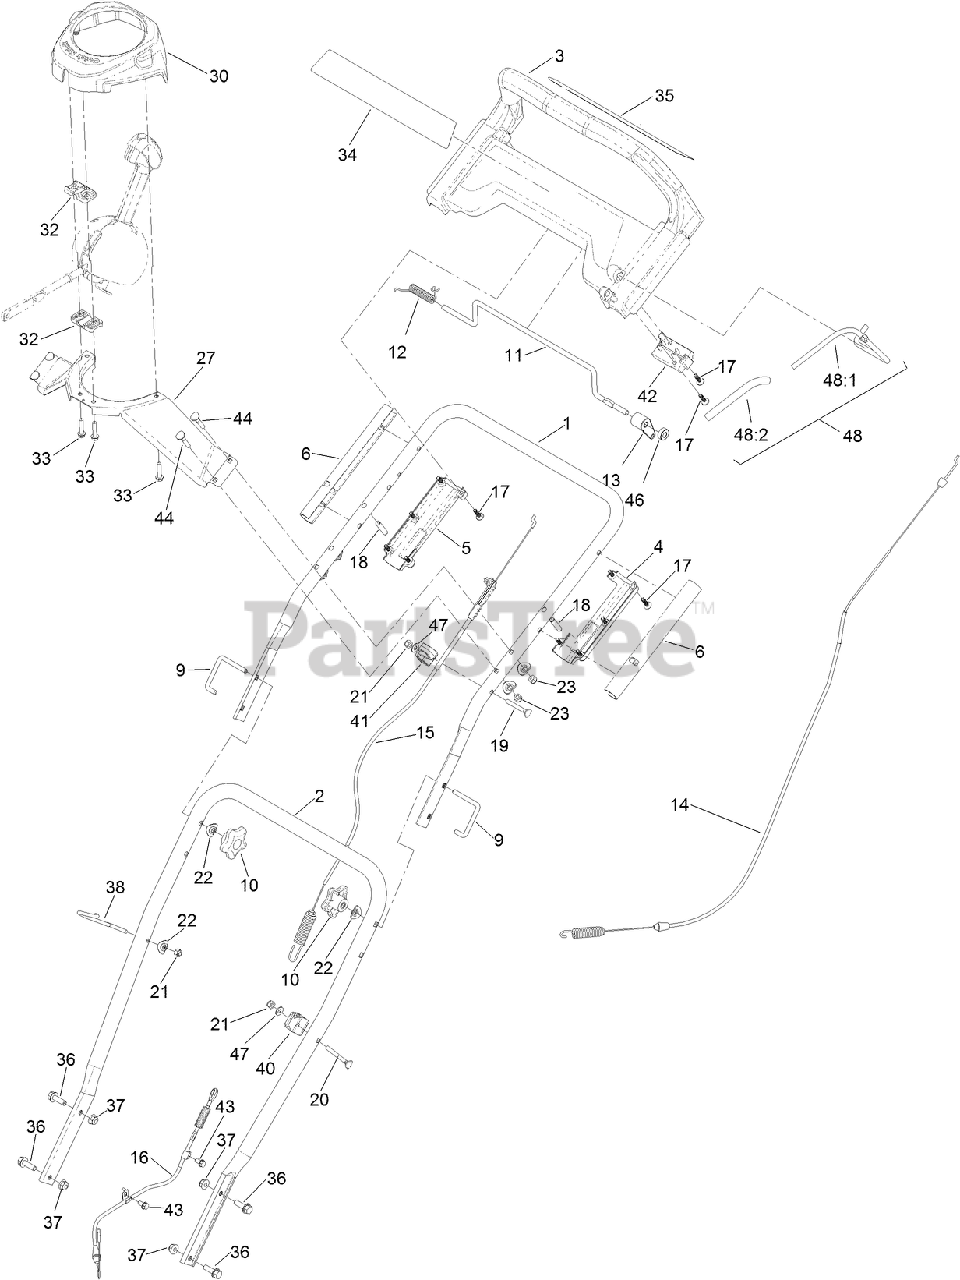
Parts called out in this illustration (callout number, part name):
1	HANDLE-UPPER
2	HANDLE-LOWER
3	HANDLE
4	HANDLE-BOTTOM, LH
5	HANDLE-BOTTOM, RH
6	SLEEVE HANDLE
10	KNOB-HANDLE
13	LEVER-TRACTION
14	CABLE-TRANSMISSION
15	CABLE-ROTOR, UPPER
16	CABLE-ROTOR, LOWER
18	PIN-DOWEL
19	SCREW
20	SCREW-HANDLE
21	NUT-LOCK, NI
22	WASHER
23	NUT-LOCK, NI
27	BRACKET-CHUTE, CONTROL
30	COVER TOP
32	SUPPORT-ROD
33	SCREW-PLASTITE
34	DECAL-DISPLAY
35	DECAL-CONTROL, PANEL
36	SCREW-HHF
37	NUT-HF, NI
38	GUIDE-ROPE
40	ANCHOR-CABLE, UPPER
41	CABLE-GUIDE
42	BAIL-MOUNT
43	SCREW-HWH
44	SCREW-HANDLE
46	SPACER
47	WASHER-FLAT
48	BAIL ASM
48:1	BAIL-AUGER
48:2	COVER-BAIL
